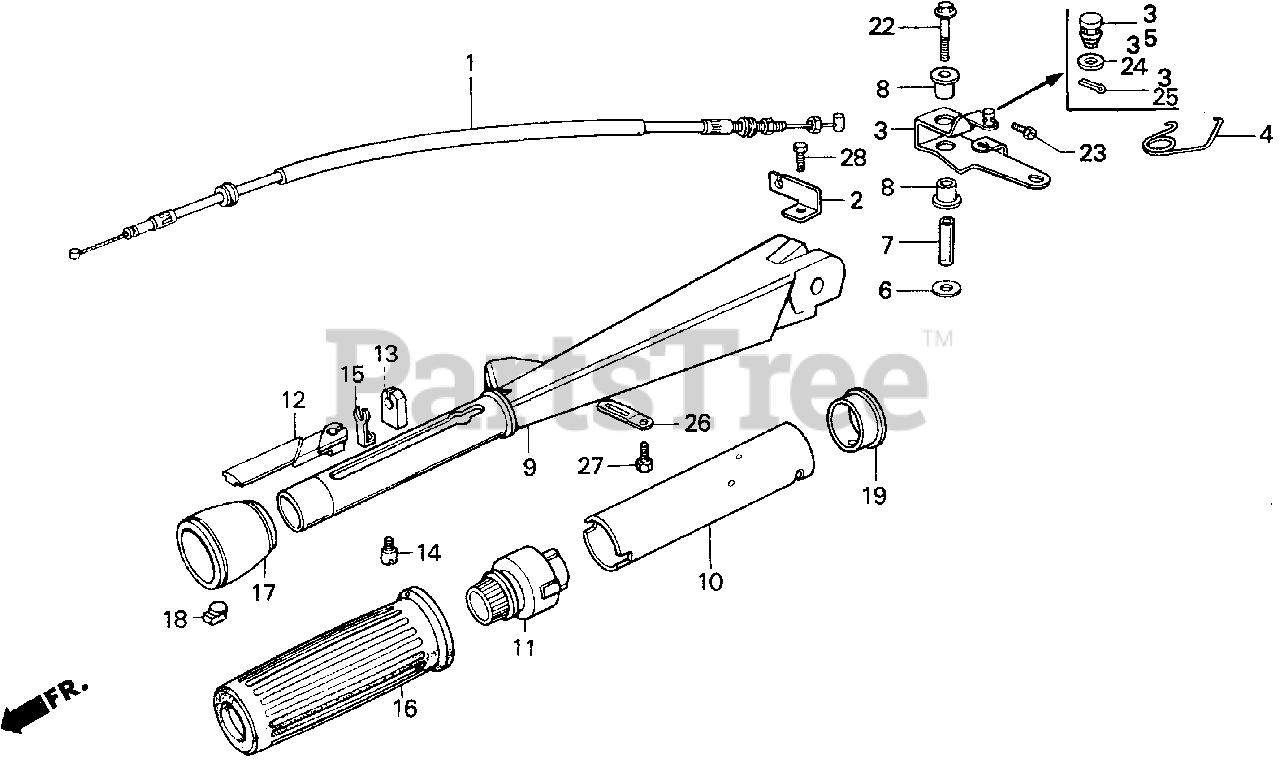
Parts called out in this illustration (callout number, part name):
1	CABLE, THROTTLE
2	HOLDER, CABLE
3	ARM, THROTTLE
4	SPRING, THROTTLE ARM
5	HOLDER, STARTER ROD
6	WASHER, PIVOT
7	COLLAR, PIVOT
8	BUSH, SHAFT
9	HANDLEBAR *NH282MU* (OYSTER SILVER METALLIC-U)
10	PIPE, GRIP
11	NUT, GRIP FRICTION
12	HINGE, THROTTLE WIRE
13	HOLDER, THROTTLE CABLE
14	STOPPER, GRIP PIPE
15	STOPPER, CABLE
16	RUBBER, GRIP
17	COVER, GRIP PIPE
18	GROMMET, HANDLE COVER
19	GUIDE B, GRIP PIPE
22	BOLT, FLANGE (6X35)
23	BOLT, STRAIGHT SLOT (4X6)
24	WASHER, PLAIN (6MM)
25	PIN, SPLIT
25	PIN, SPLIT (2.0)
26	CLIP, WIRE
27	BOLT, HEX. (6X12)
28	BOLT, HEX. (6X12)
